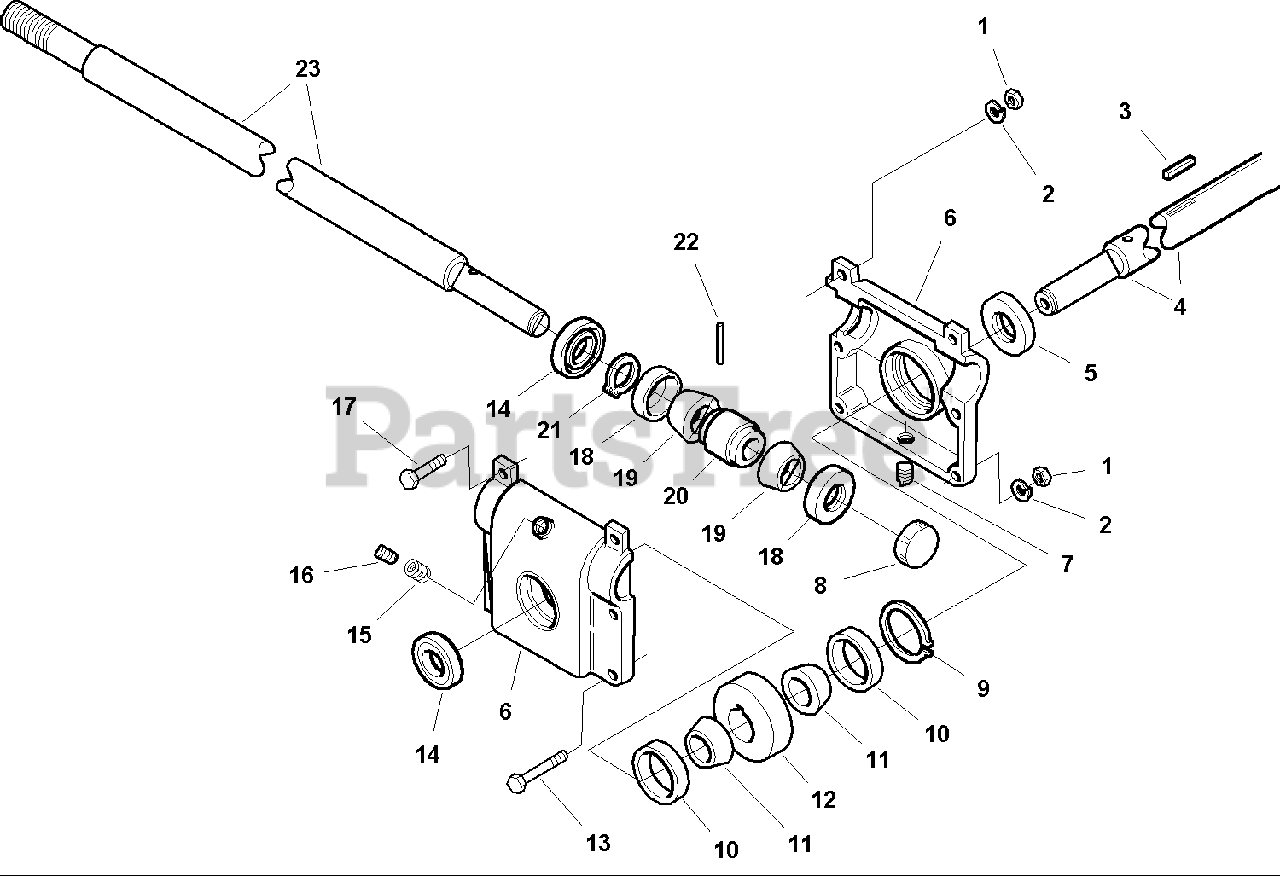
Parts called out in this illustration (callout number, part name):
1	NUT, Hex, 5/16-18
2	LOCKWASHER, 5/16
3	KEY, 1/4 x 1/4 x 5/8
4	SHAFT, Output
5	SEAL, Oil, 1.0 ID x 2.0 OD
6	CASE, Gearbox (2-halves)
7	VENT, Relief
9	RING, Retaining
10	RACE, Bearing
11	BEARING, Roller
13	CAPSCREW, Hex Head, 5/16-18 x 2-1/2
15	FITTING, Reducer, 1/4 Male x 1/8 Female
16	PLUG
17	CAPSCREW, Hex Head, 5/16-18 x 1-1/4
18	RACE, Bearing
19	BEARING, Roller
21	RING, Retaining
22	PIN, Dowel, 1/4 x 1-1/8
23	SHAFT, Input
